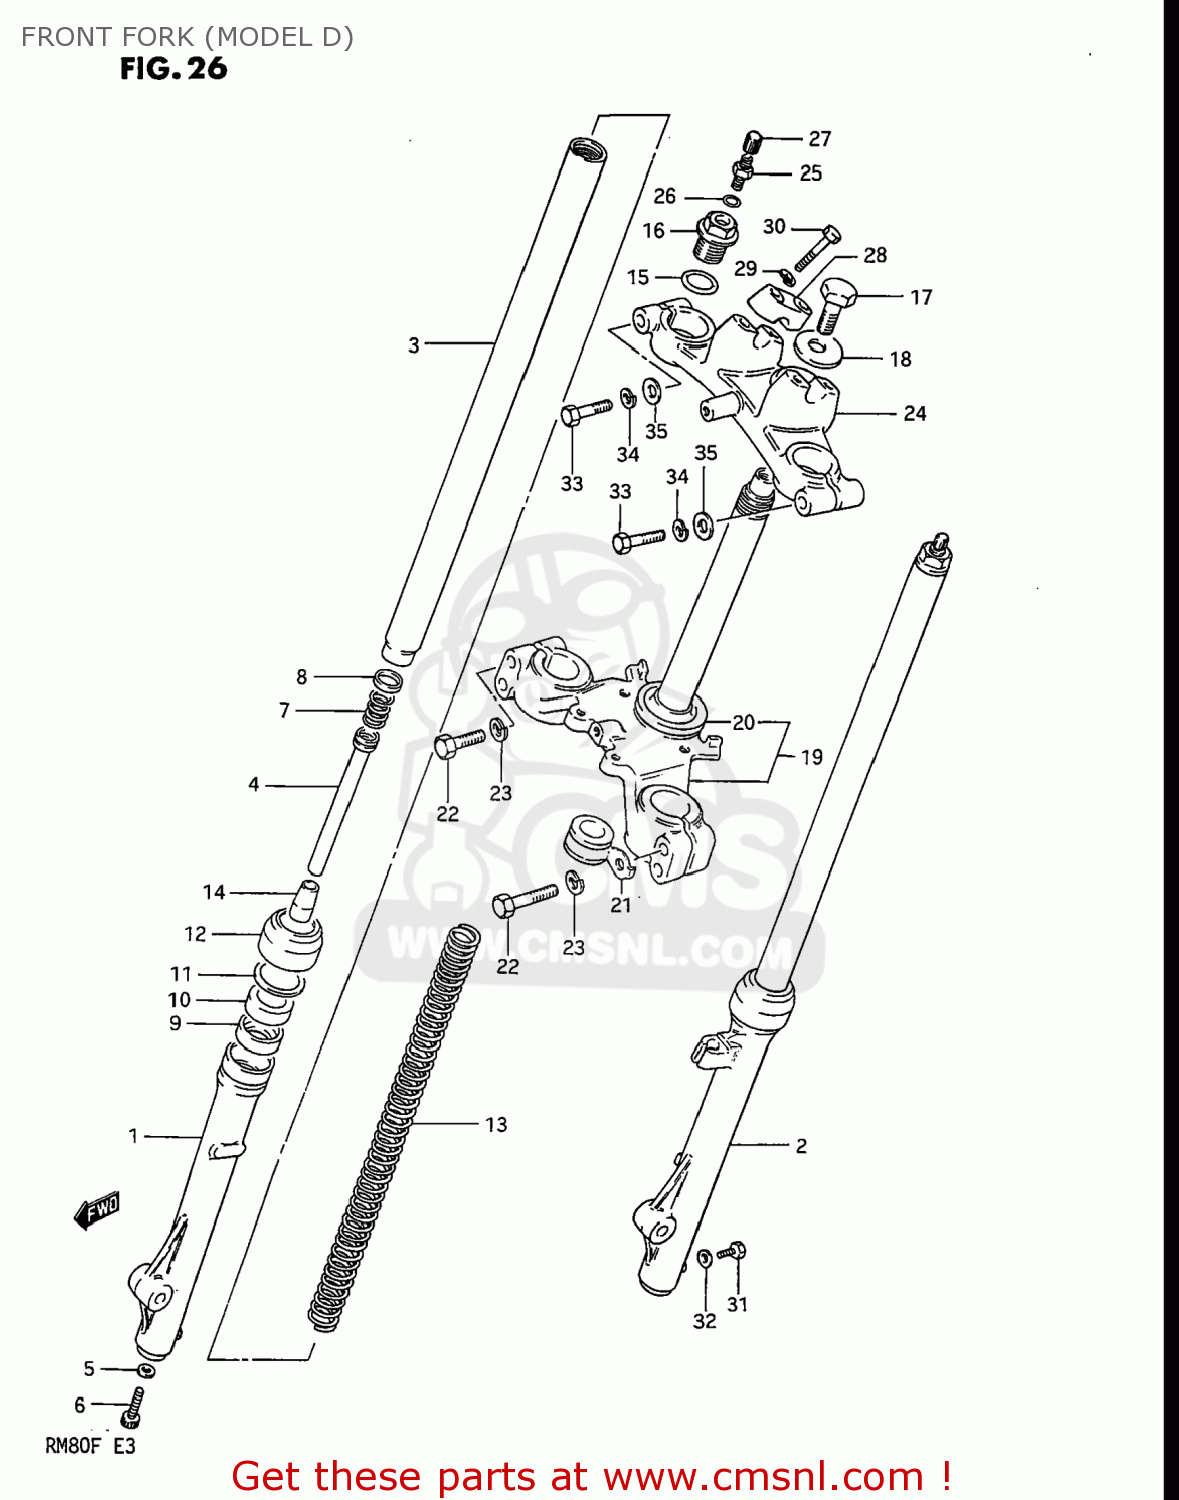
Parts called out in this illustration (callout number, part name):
1	TUBE,OUTER,RIGHT
2	TUBE,OUTER,LEFT
3	TUBE,INNER
4	CYLINDER,FRONT FORK
5	GASKET (NAS)
6	BOLT(8X27)
7	SPRING,REBOUND
8	RING,PISTON
9	SPACER,FORK OIL SEAL
10	SEAL,OIL
11	CIRCLIP,FORK OIL SEAL
12	SEAL,DUST
13	SPRING,FRONT FORK
14	PIECE,OIL LOCK
15	O RING
16	BOLT,FORK INNER TUBE
17	BOLT,STEERING STEM HEAD
18	WASHER
19	STEM,STEERING
20	RACE,STEERING OUTER LWR
21	GUIDE,CABLE
22	BOLT,FORK INNER TUBE F
23	LOCK WASHER
24	STEM HEAD,STEERING
25	VALVE,AIR
26	O-RING (D:3.8 ID:19)
27	CAP
28	HOLDER,HANDLEBAR
29	LOCK WASHER
30	BOLT
31	BOLT
32	GASKET,DRAIN,PLUG (NAS)
33	BOLT 8X40
34	LOCK WASHER
35	WASHER
